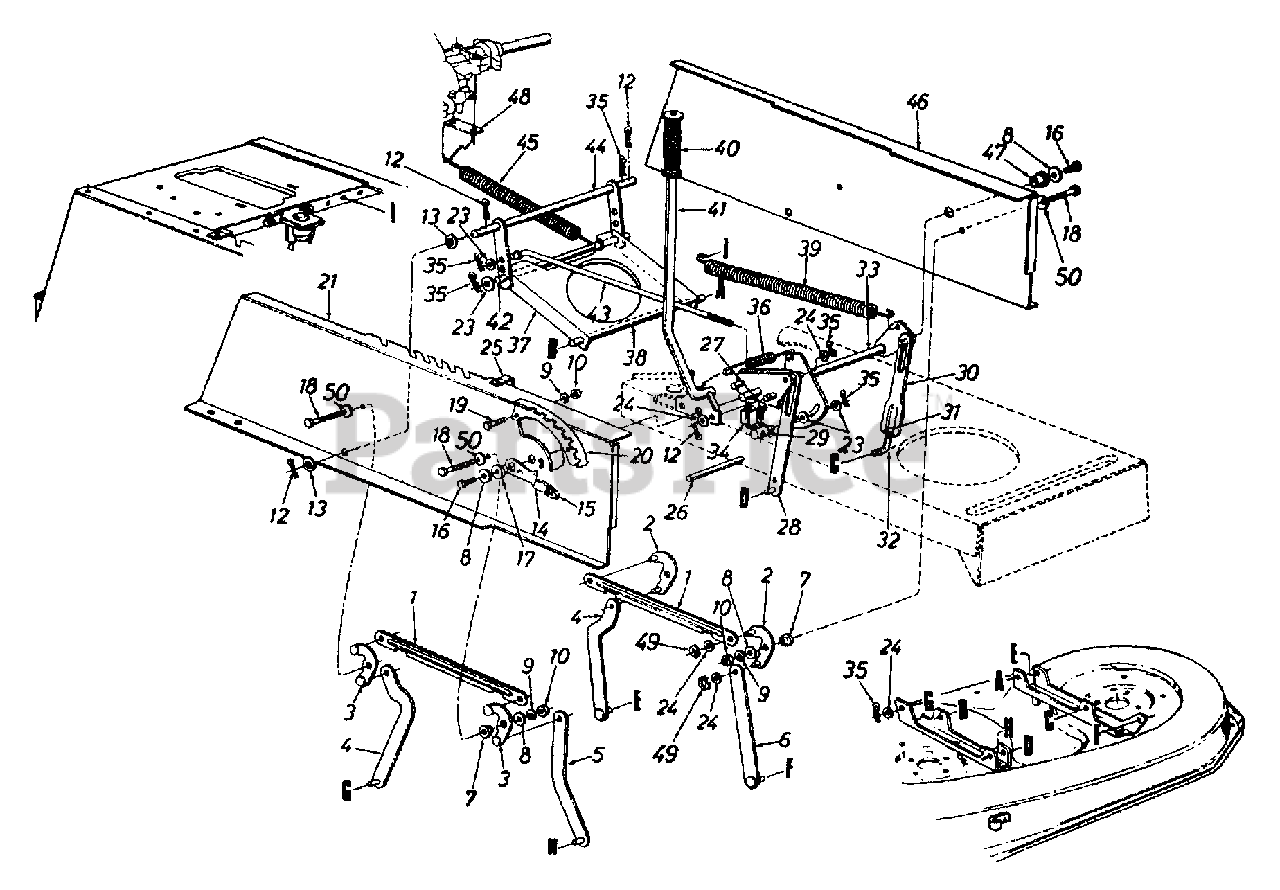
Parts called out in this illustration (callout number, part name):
3	Pivot Link Ass'y.-R.H.
7	Shld. Spacer .318" I.D.
8	Fl-Wash. .344" I.D. x 1.125" O.D.
9	L-Wash. 5/16" I.D.
10	Flange Lock Nut 5/16-18 Thd. (Gr. 5)
12	Cotter Pin 1/8" Dia.
13	Fl-Wash. .635" I.D. x 1.0" O.D.
14	Hgt Adj. Stop Lever Ass'y.
15	Knob
16	Hex Wash. TT-Tap Scr. 5/16-18 x .75"
17	Flange Brg. .63" I.D.
18	Hex Wash. Hd. Scr. 5/16-18 x .875" Lg.
19	Hex Bolt 5/16-18 x .75" Lg.
20	Index Brkt.
24	Fl-Wash. .531" I.D. x .93" O.D.
25	Clamp
26	Running Board Rod
27	Hex Wash. Hd. Tap Scr.
31	Hex Nut 1/2-20 Thd. (Gr. 5)
32	Lift Link Adjuster
35	Inter. Cotter Pin 3/8" Dia.
36	Extension Spring
39	Extension Spring
40	Grip (Lift Handle)
43	Disengagement Rod
46	Upper Frame-L.H.
47	Flange Brg. .632" I.D.
49	"E"-Ring
50	Bell-Wash. .325" I.D.
